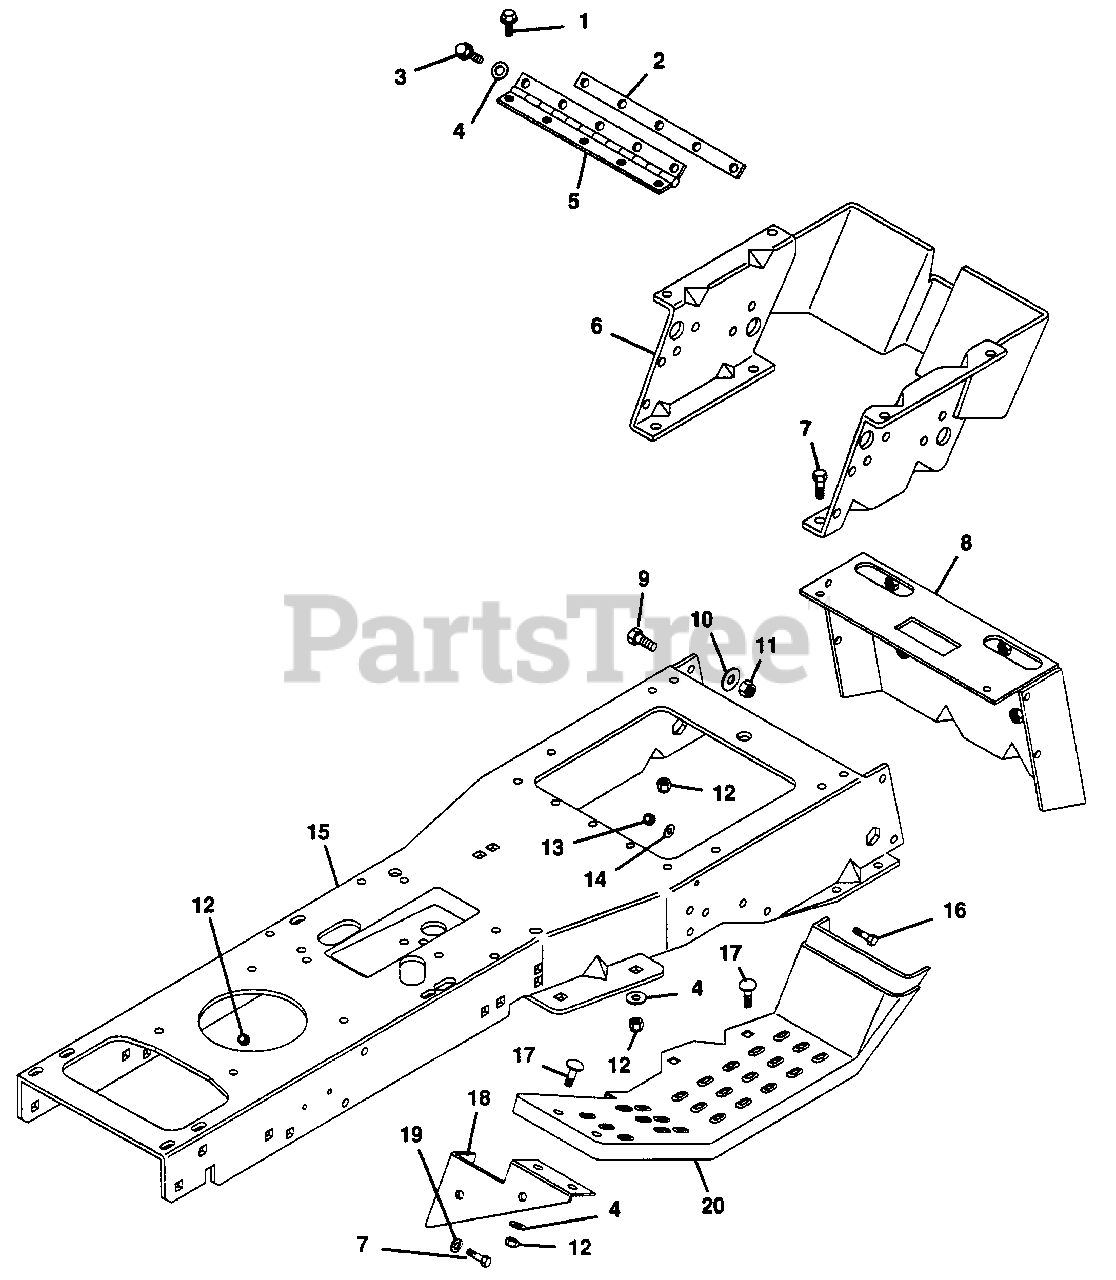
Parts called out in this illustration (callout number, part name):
1	Screw, Taptite 5/16-18 x .75
2	Strap
3	Screw, Taptite 5/16-18 x .50
4	Washer, Flat .344 x .688 x .065
5	Hinge
6	Deck, Support
7	Bolt, Hex 5/16-18 x 1.00
8	Weldment, Tailboard
9	Bolt, 3/8-16 x .875
10	Washer, Flat .375 x 1.125 x .065
11	Nut, Lock 3/8-16
12	Nut, Lock 5/16-18
13	Nut, Lock 1/4-20
14	Washer, Flat .281 x .625 x .065
15	Frame
16	Bolt, Hex 1/4-20 x .750
17	Bolt, Carriage 5/16-18 x 1.0
18	Foot Rest Brace, L.H.
18	Foot Rest Brace, R.H.
19	Washer, Flat .313 x .875 x .065
20	Foot Rest, L.H.
20	Foot Rest, R.H.
NS	Decal, Transmission Lockout
